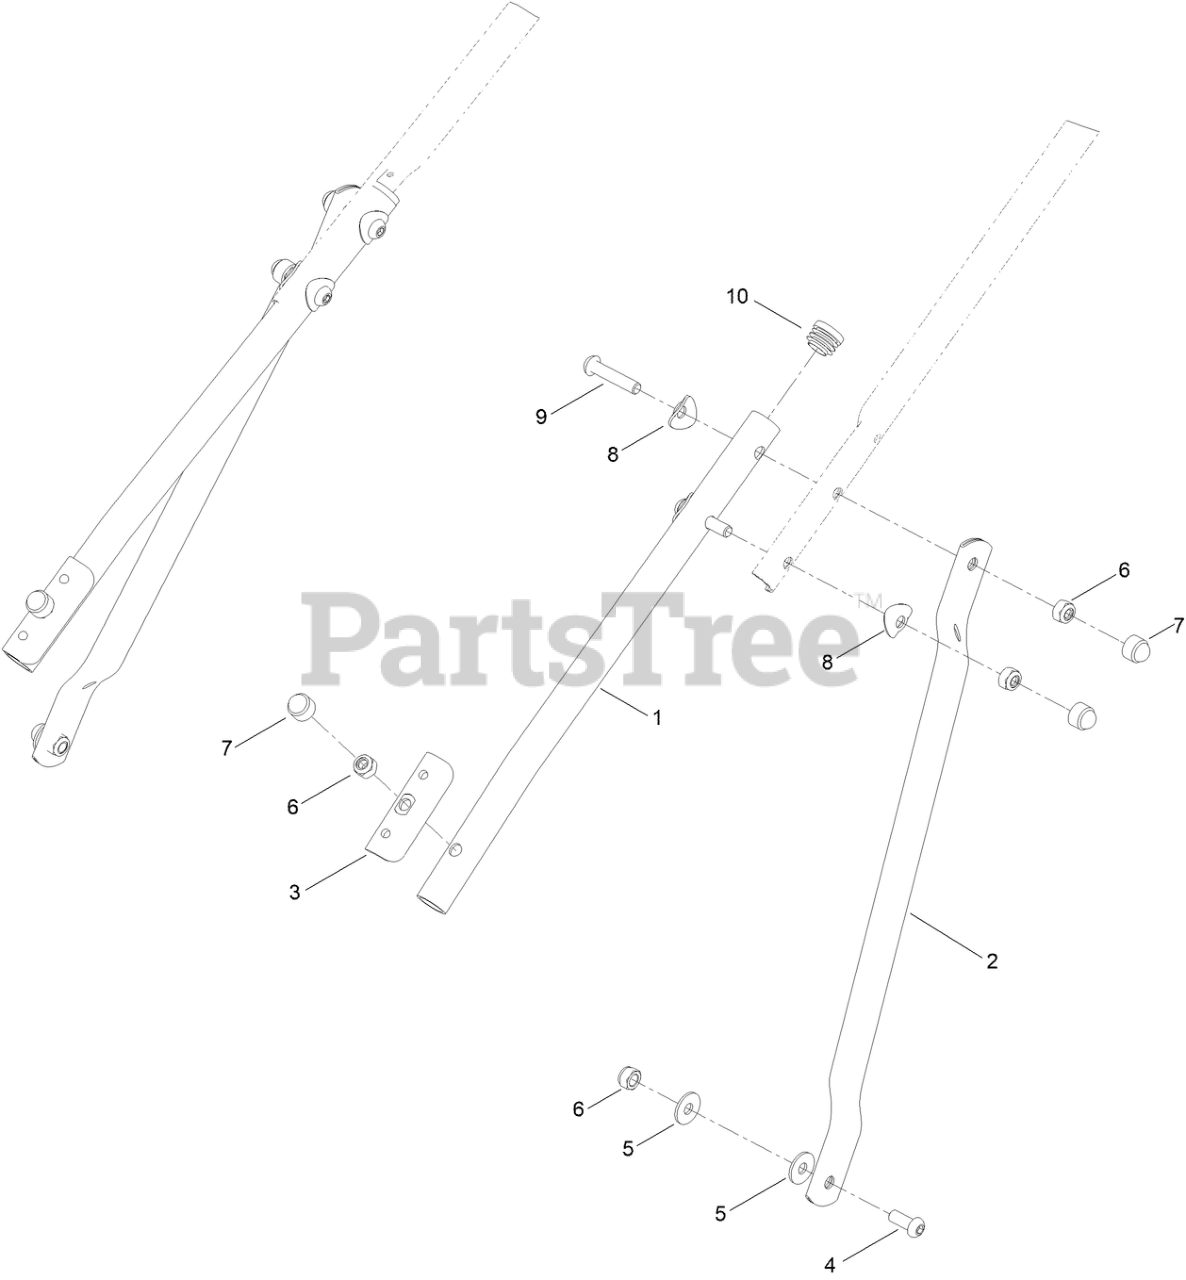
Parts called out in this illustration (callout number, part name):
1	HANDLEBAR LOWER (PROSTRIPE)
2	PROSTRIPE BRACE HANDLEBAR
3	PLATE-CLAMP, HANDLEBAR
4	SCREW-HSBH
5	WASHER
6	NUT-HEX, NI
7	CAP-NUT
8	WASHER-CUP
9	SCREW-HSBW
10	PLUG-TUBE
